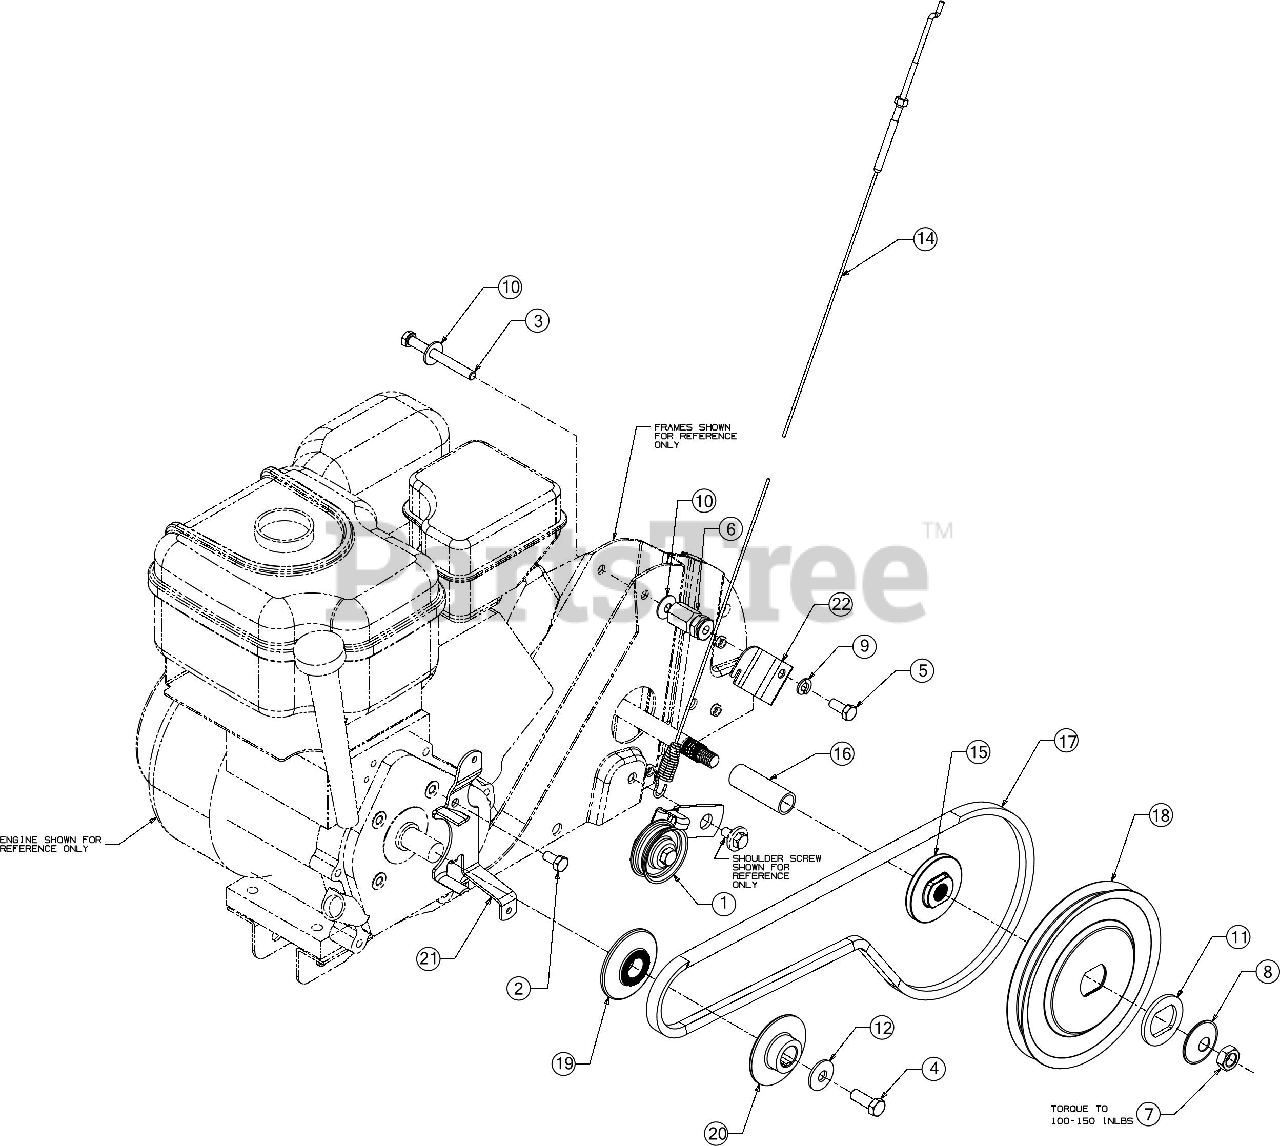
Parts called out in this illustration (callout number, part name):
1	IDLER BRACKET ASSEMBLY
1	SCREW 3/8-16 X 1.25 GR5
1	JAM LOCK NUT
1	IDLER PULLEY
1	IDLER BRACKET
1	BELT KEEPER
2	HEX SCREW 5/16-24 X .62
3	HEX SCREW 5/16-18 X 3.00
4	SCREW 3/8-24 X 1.00 GR8
5	SCREW 5/16-18 X .75 GR5
6	SPECIAL HEX NUT
8	BELL WASHER .535 ID X1.50 OD X.052
9	LOCK WASHER 5/16
10	BELL WASHER .337 X.867 X .057
11	RETAINING WASHER
12	BELL WASHER
14	CABLE
15	PULLEY MOUNTING ADAPTER
16	SPACER
17	V-BELT
18	PULLEY
19	ENGINE PULLEY INNER HALF
20	ENGINE PULLEY OUTER HALF
21	BELT COVER BRACKET
22	CABLE BRACKET GUIDE
